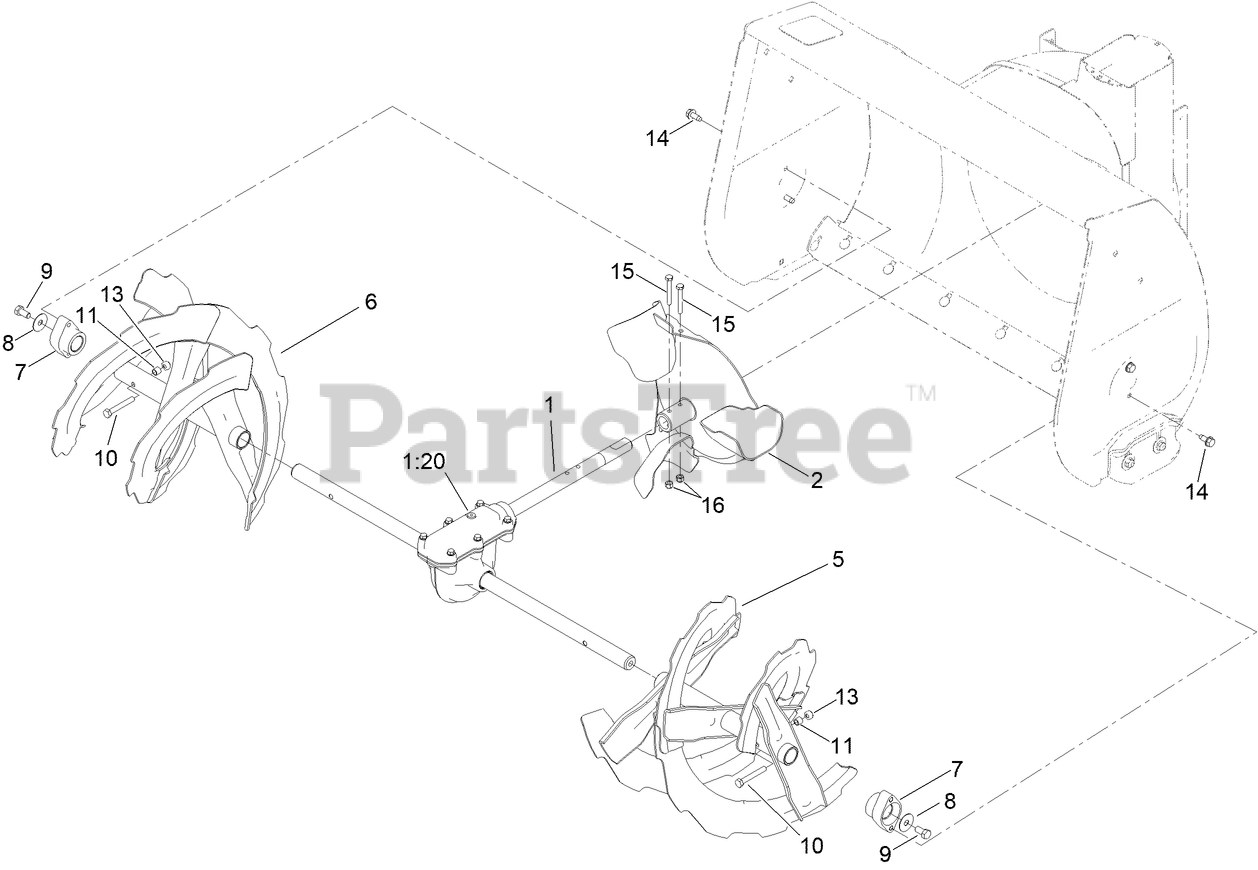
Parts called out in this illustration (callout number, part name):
1	AUGER GEARCASE ASM
1:20	PLUG-OIL
2	IMPELLER
5	AUGER-LH, 32 INCH
6	AUGER-RH, 32 INCH
7	BEARING-AUGER
8	WASHER
9	SCREW-HH
10	SCREW-HH
11	SPACER-GROMMET
13	NUT-HEX
14	SCREW-HWHTF
15	SCREW-HH
16	NUT-HEX
